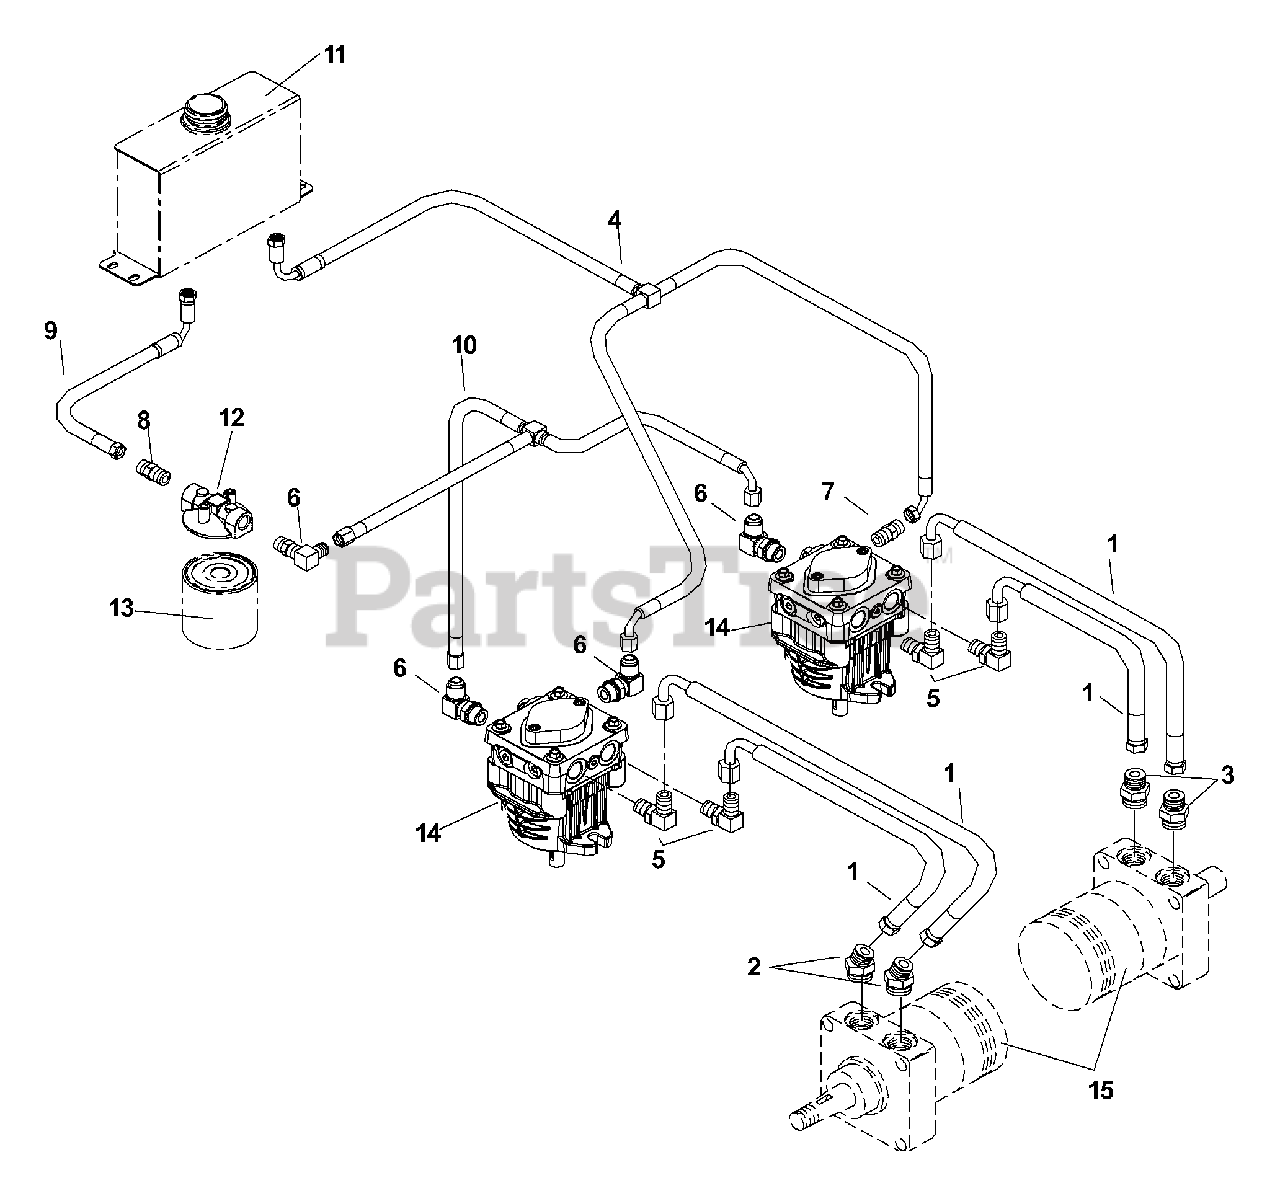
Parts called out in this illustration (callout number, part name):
1	HOSE
2	45 DEGREE ELBOW
3	STRAIGHT CONNECTOR
5	90 DEGREE ELBOW
6	90 DEGREE ELBOW
8	STRAIGHT CONNECTOR
9	HOSE
12	FILTER HEAD
14	PUMP, 10A W/.031 POPPETS
15	HYD. MOTOR
